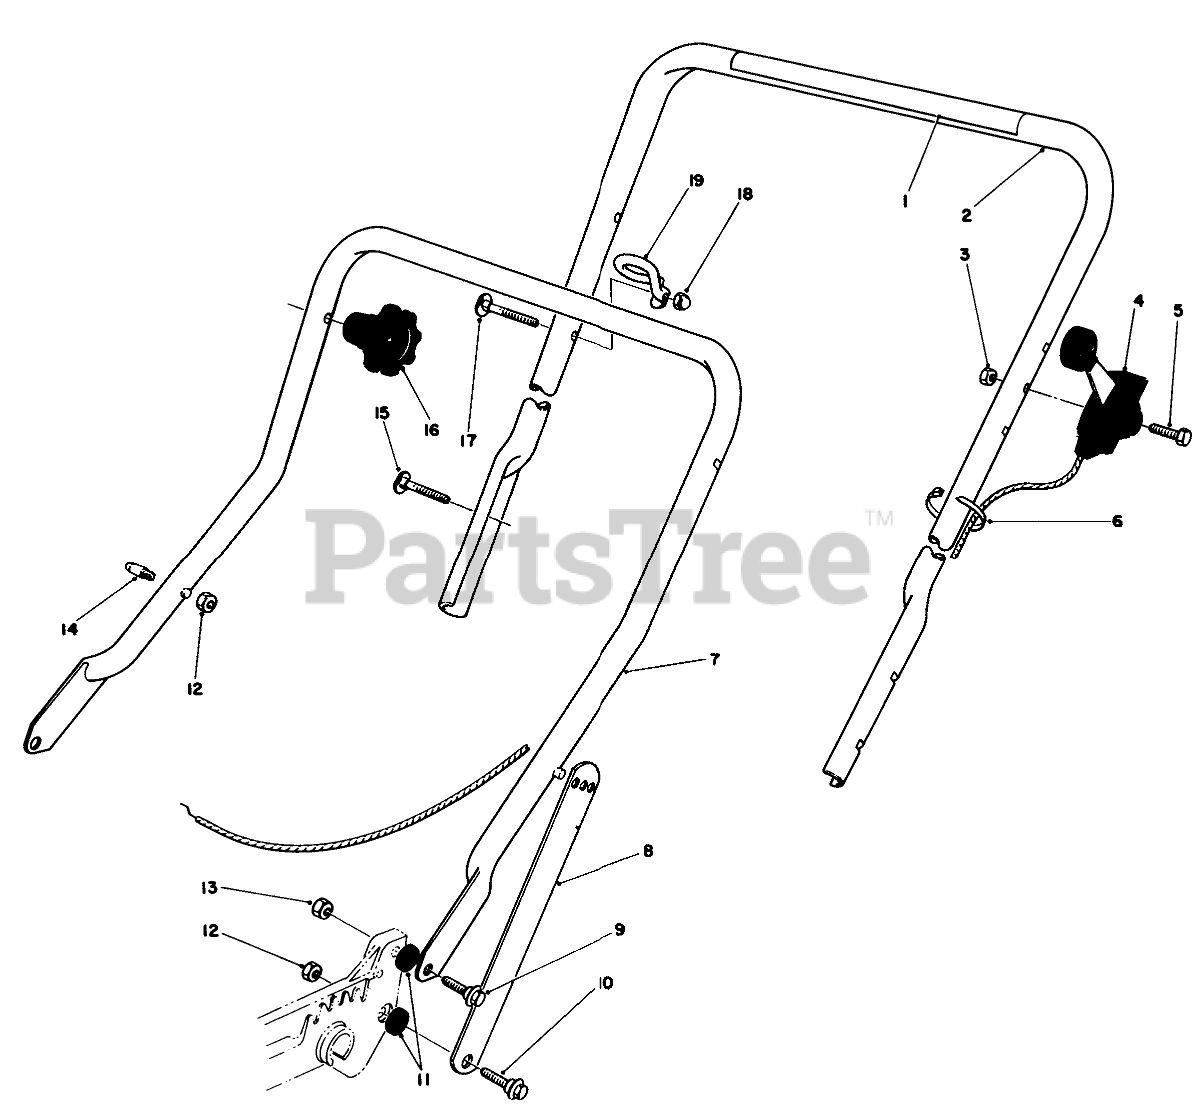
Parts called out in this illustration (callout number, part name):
1	Decal-Instructions
2	Handle-Upper
3	Locknut
4	SERVICE THROTTLE CONTRO
5	SCREW-HH
6	TIE-CABLE
7	Handle-Lower
8	Handle Latch
9	SCREW-SHOULDER
10	SCREW-SHOULDER
11	SPACER
12	NUT-LOCK, NI
13	NUT-LOCK, NI
14	HANDLE PIN
15	5/16-18 X 2 HNDLE SCREW
17	HANDLE SCREW
18	NUT-CAP
19	Guide
